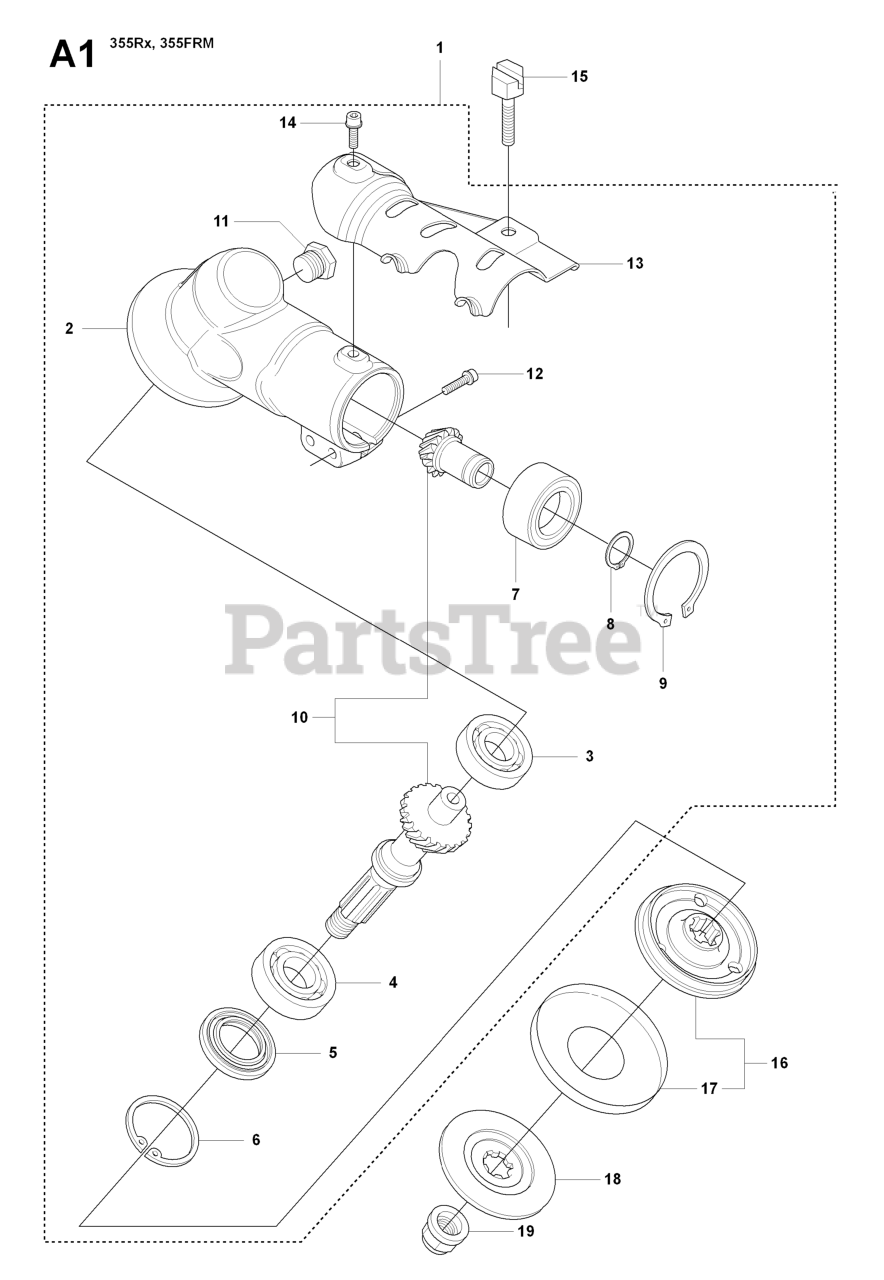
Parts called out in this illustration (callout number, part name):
1	BEVEL GEAR
2	GEAR HOUSING
3	BALL BEARING
4	BALL BEARING
6	RETAINING RING SGH 35
8	RETAINING RING SGA 15
9	RETAINING RING
10	BEVEL GEAR
13	ATTACHMENT PLATE
16	RP CARRIER
17	GRASS SEALING
18	SUPPORT FLANGE
19	BLADE NUT
